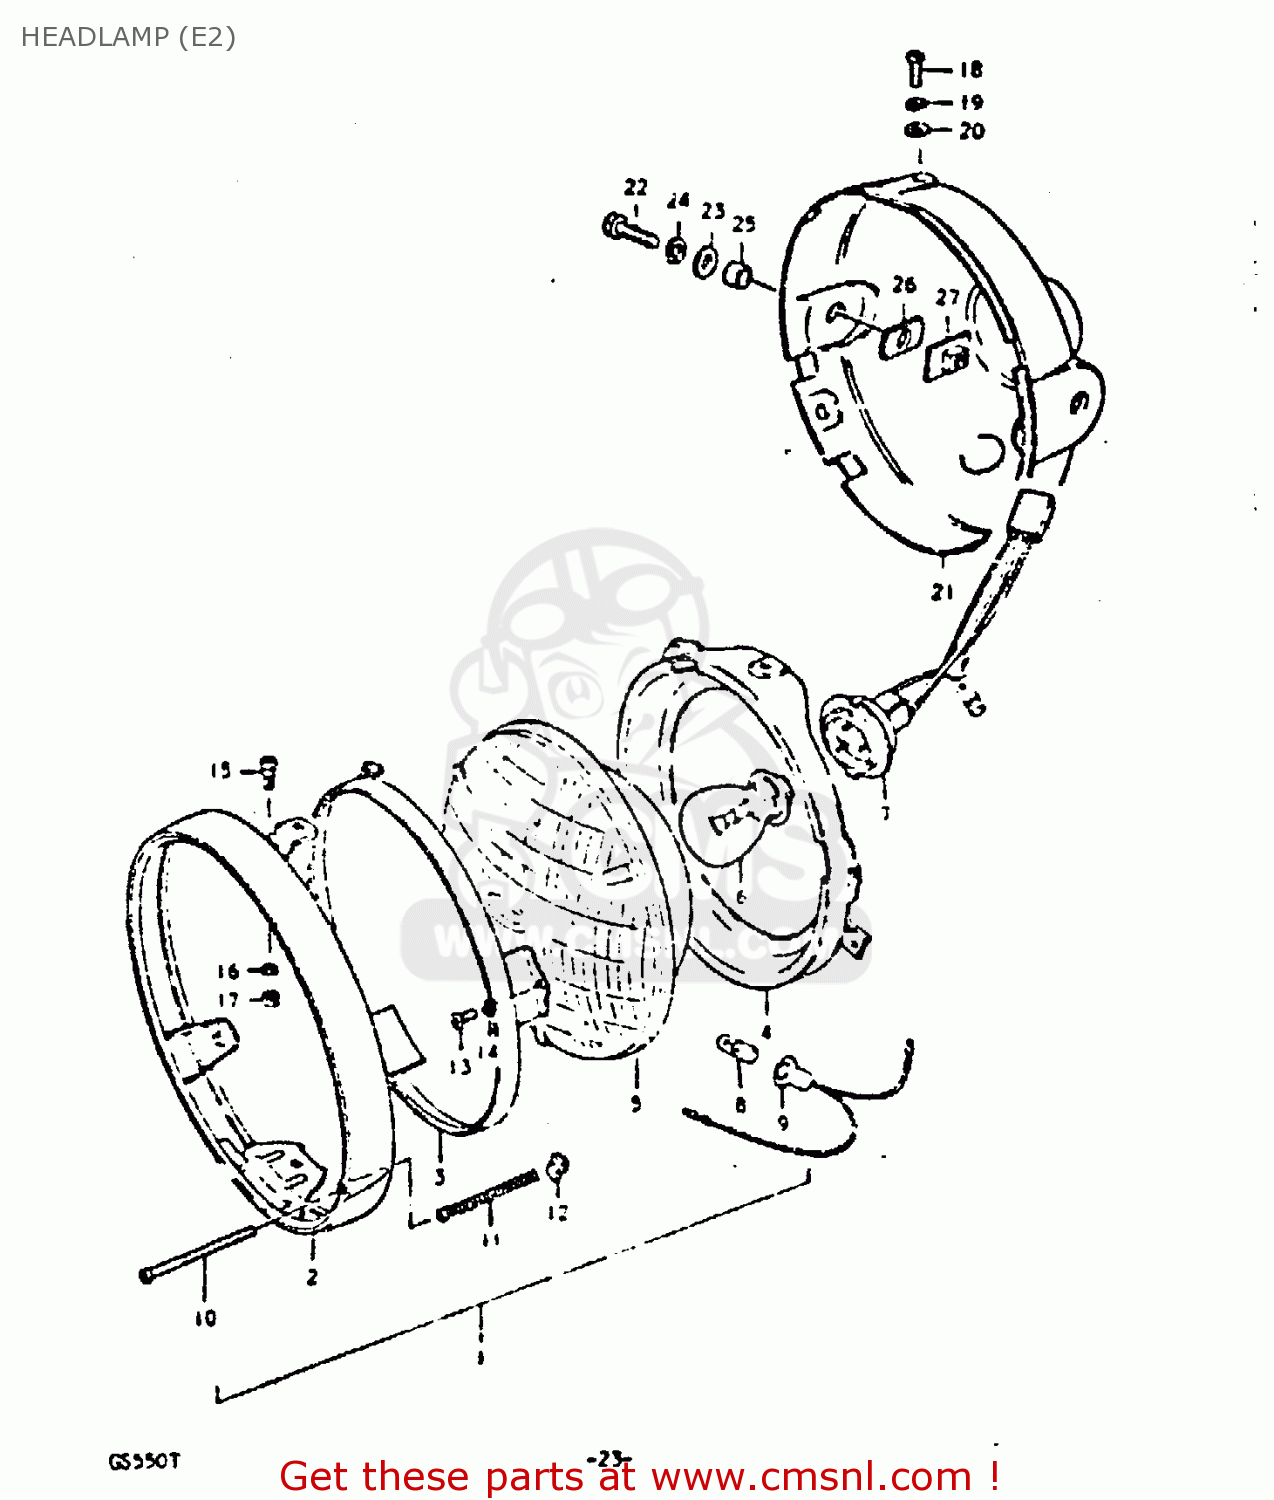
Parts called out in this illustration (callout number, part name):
1	HEADLAMP ASSY
2	RIM
3	RETAINING RING
4	RING
5	LAMP UNIT
6	BULB
7	SOCKET,HEADLAMP
8	BULB
9	SOCKET
10	SCREW,HEADLAMP ADJUST
11	SPRING,ADJUSTING
12	NUT
13	SCREW
14	LOCK WASHER
15	H/LAMP LENS UNIT FITING SCRE
16	LOCK WASHER
17	NUT
18	SCREW
19	WASHER,LOCK
20	WASHER
21	HOUSING,HEADLAMP(BLACK)
22	BOLT
23	WASHER
24	LOCK WASHER
25	SPACER (8.8X12X7)
26	CUSHION
27	PLATE,HEADLAMP HOUSING
